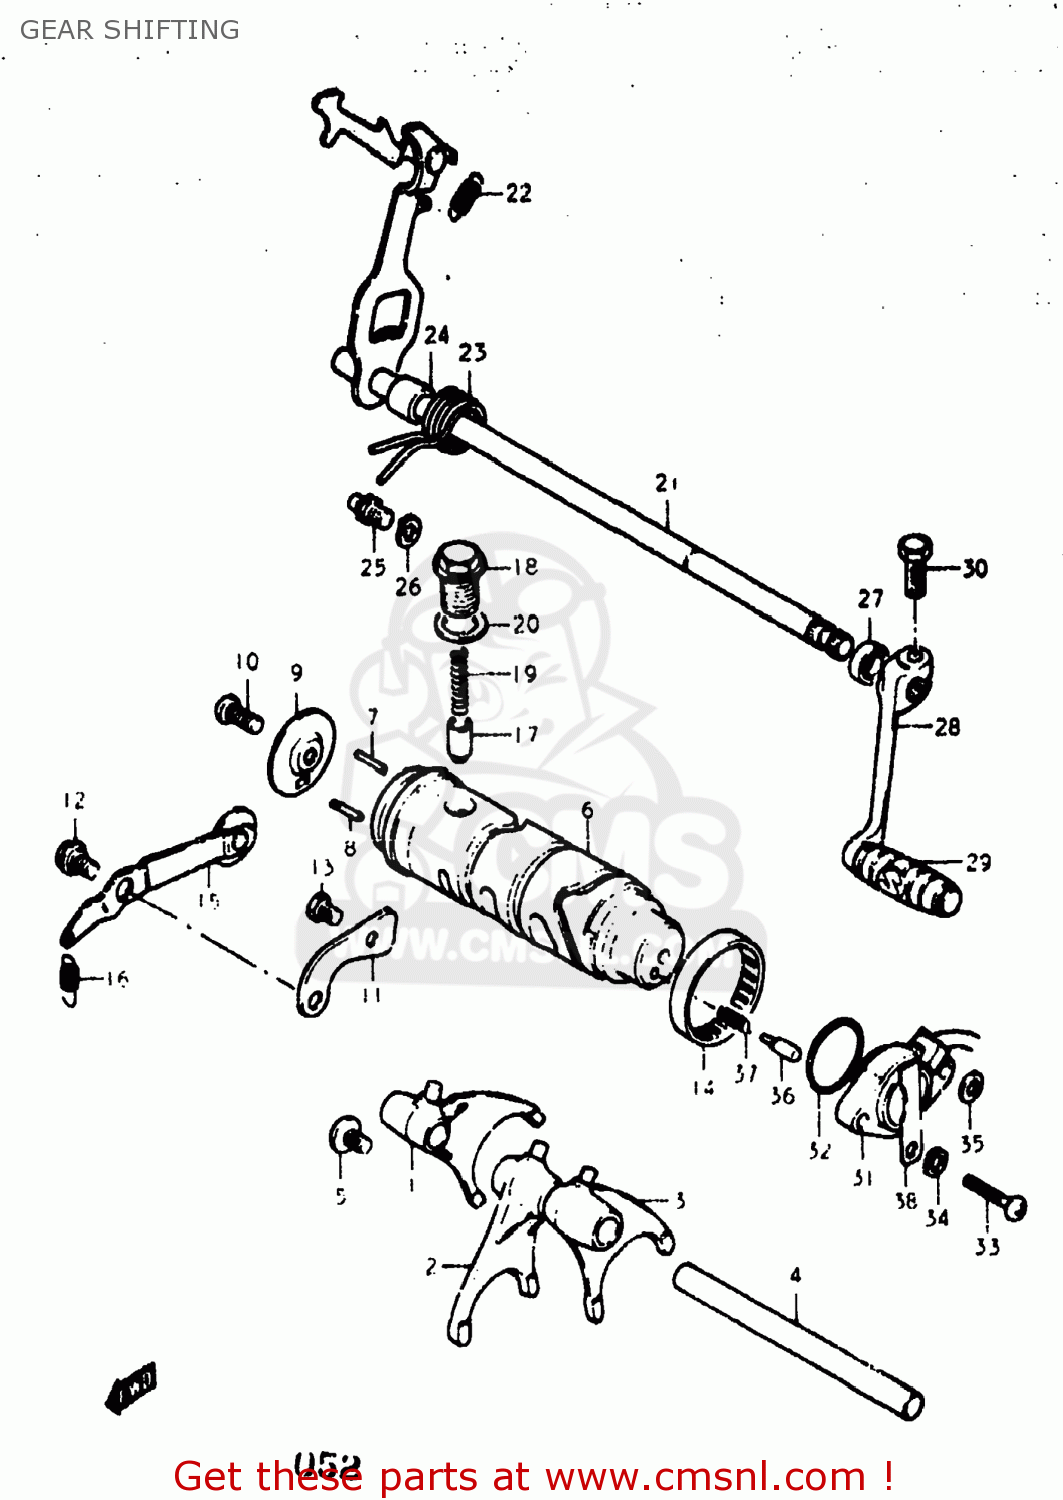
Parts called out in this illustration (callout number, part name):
1	FORK,GEAR SHIFT NO.1
2	FORK,GEAR SHIFT NO.2
3	FORK,GEAR SHIFT NO.2
4	SHAFT,GEAR SHIFT FORK
5	SCREW
6	CAM,GEAR SHIFT
7	PIN(4X18.5)
8	PIN
9	RETAINER,GEAR SHIFT CAM DR PIN
10	SCREW
11	GUIDE,GEAR SHIFTING CABLE
12	BOLT
13	BOLT
14	BEARING(40X47X12)
15	STOPPER,GEAR SHIFT CAM NO.1
16	SPRING
17	STOPPER,GEAR SHIFTING
18	BOLT,GEAR SHAFT CAM STOPPER
19	SPRING
20	GASKET(14X19.2X2) (NAS)
21	SHAFT,GEAR SHIFT
22	SPRING
23	SPRING
24	SPACER(12X20X15.3)
25	STOPPER,GEAR SHIFT CAM
26	LOCK WASHER
27	OIL SEAL
28	LEVER ASSY,GEAR SHIFT
29	RUBBER,GEAR SHIFT PEDAL
30	BOLT
31	BASE ASSEMBLY,NEUTRAL SWITCH TERMINAL
32	O-RING (D:2.4 ID:26.2)
33	SCREW
34	LOCK WASHER
35	WASHER
36	PIN(5X15.5)
37	SPRING
38	CLAMP,GENERATOR LEAD WIRE
